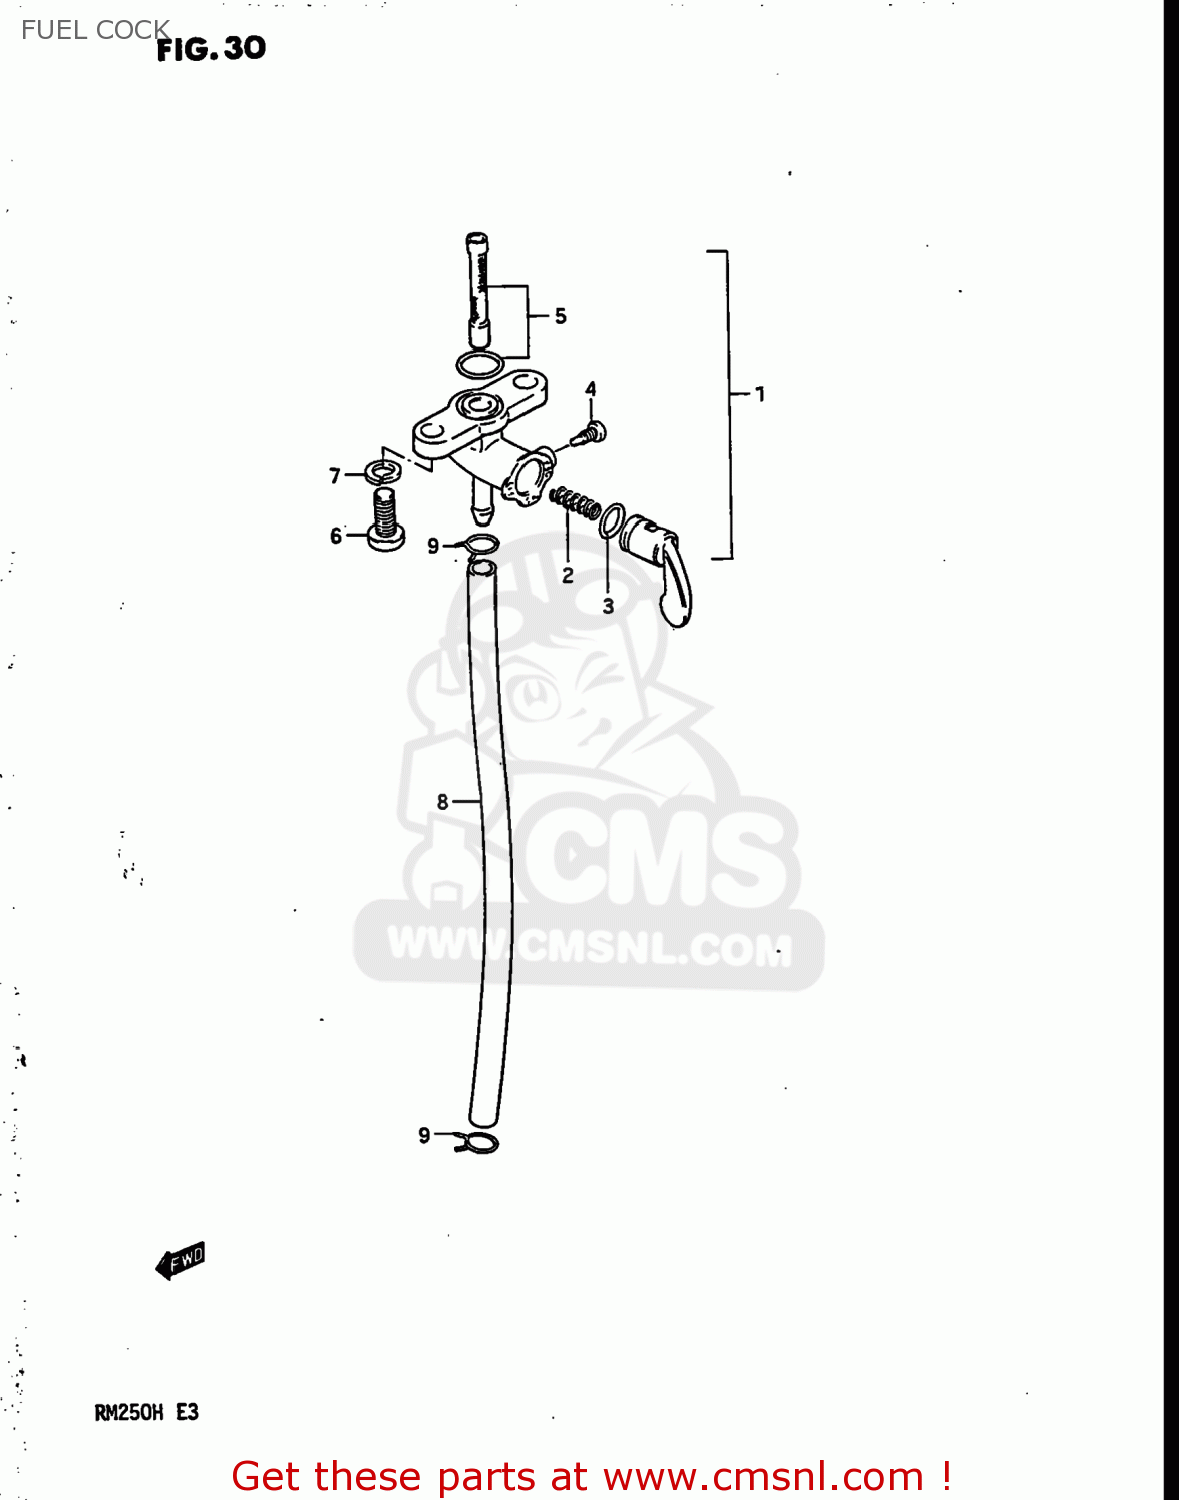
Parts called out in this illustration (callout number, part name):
1	COCK ASSY,FUEL
2	SPRING,FUEL COCK VALUE
3	O RING,LEVER
4	SCREW
5	FILTER SET FUEL
6	SCREW
7	WASHER,LOCK
8	HOSE
9	CLIP
